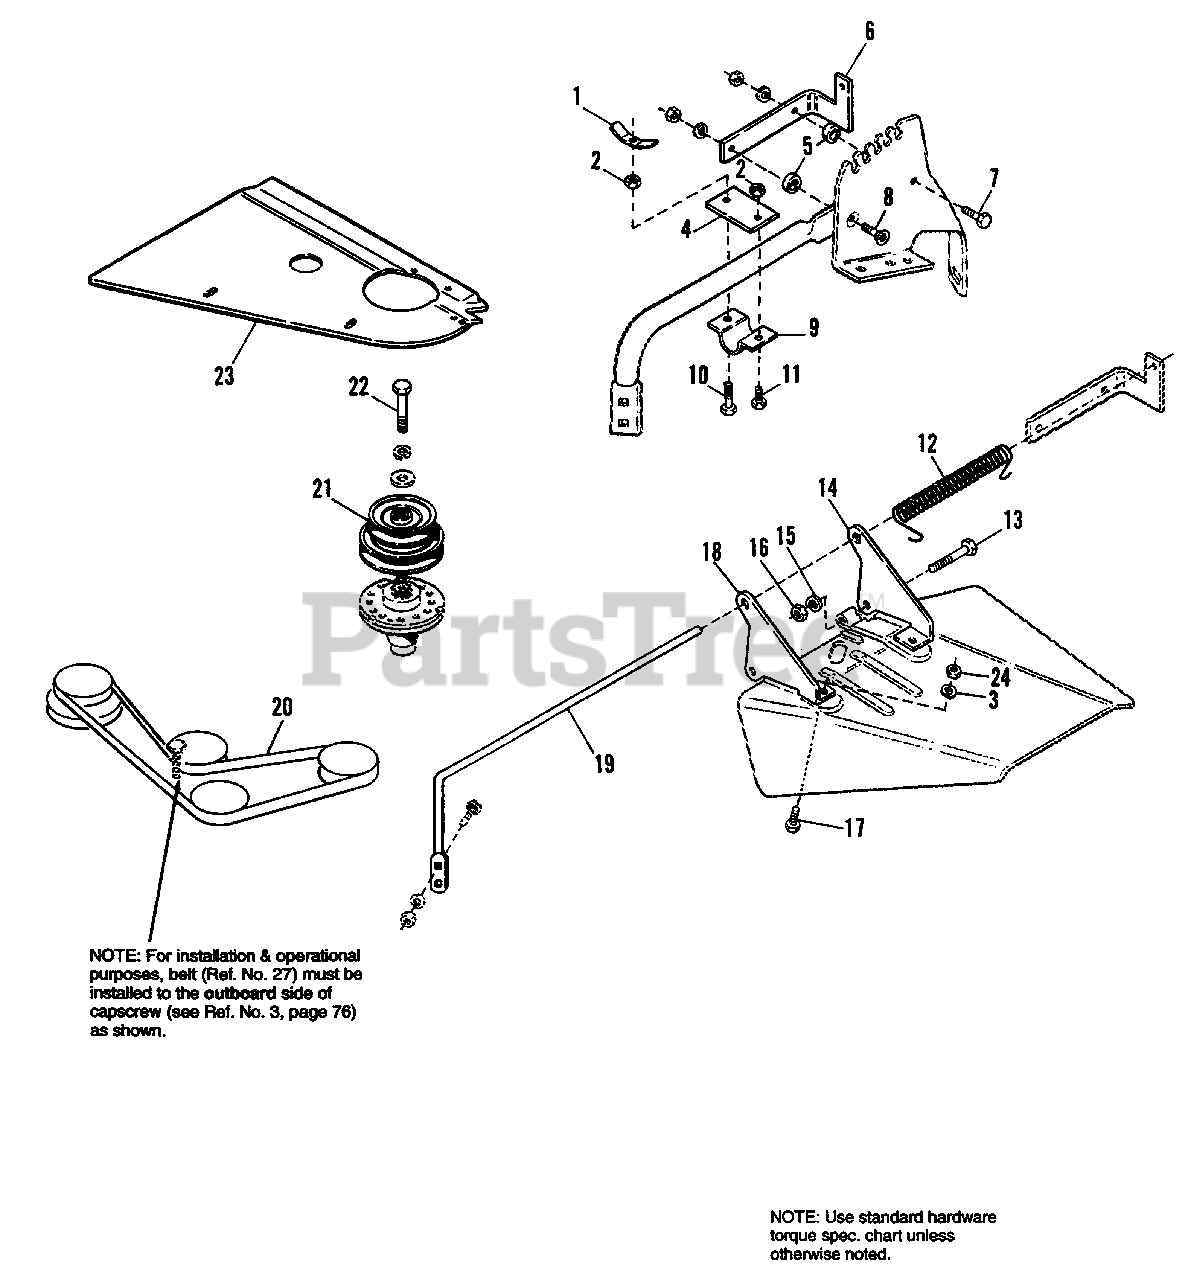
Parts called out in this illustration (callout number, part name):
2	NUT, Hex Jam Lock, 5/16-18
3	LOCKWASHER, 5/16
4	CLAMP, Upper
6	PIVOT ASSY., Deflector
7	CAPSCREW, Hex, 5/16-18 x 1-1/4
8	SCREW, Flat Hd., Hex Soc., 5/16-18 1-3/4
9	CLAMP, Lower
10	CAPSCREW, Hex Hd., 5/16-18 x 1-1/4
11	CAPSCREW, Hex Hd., 5/16-18 x 5/8
12	SPRING, Torsion
13	CAPSCREW, Hex Hd., 7/16-14 x 2-1/4
14	PIVOT, Bracket, R.H.
15	LOCKWASHER, 7/16
16	NUT, Hex, Full, 7/16-14
17	CAPSCREW, Hex, 5/16-18 x 7/8
18	PIVOT, Bracket, L.H.
21	PULLEY ASSY.
22	CAPSCREW, Hex Hd., 7/16-14 x 2-1/4
23	COVER, L.H., Mower
24	NUT, Hex, Full, 5/16-18
